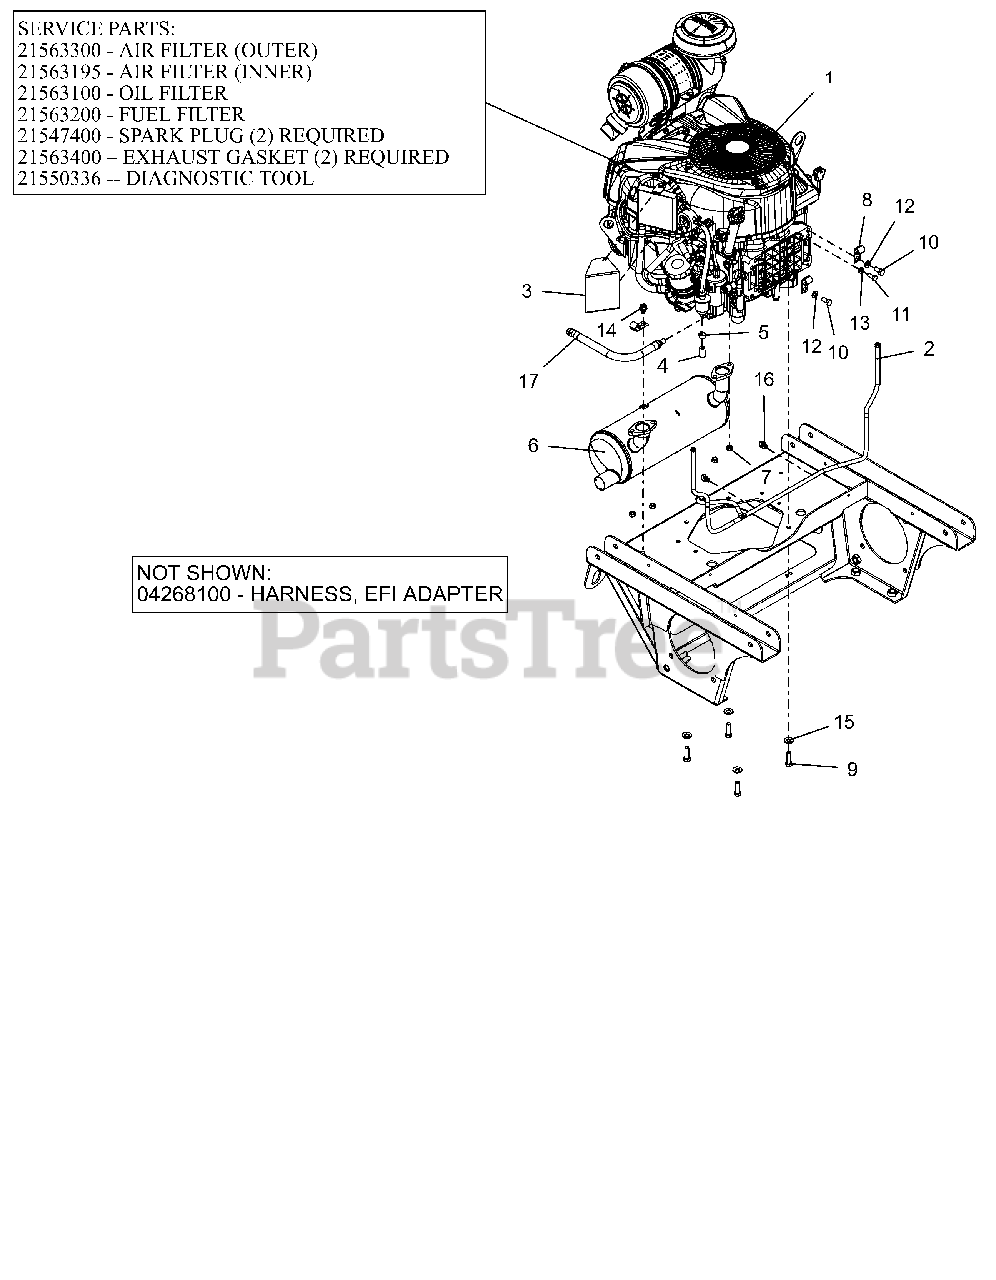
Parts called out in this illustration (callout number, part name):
1	ENGINE, YAMAHA MX775V-EFI
1	AIR FILTER (OUTER) - YAMAHA
1	AIR FILTER (INNER) - YAMAHA
1	FILTER, OIL - YAMAHA 824
1	FILTER-FUEL YAMAHA 824
1	PLUG, SPARK
1	GASKET, MUFFLER YAMAHA 824
1	DIAGOSTIC TOOL, YAMAHA MXV
2	ASM, YAMAHA VAPOR LINE
3	DEFLECTOR,YAMAH OIL COOLER AIR
4	HOSE, .25 LOW-PERM BULK GAS
5	CLAMP, FUEL LINE
6	MUFFLER, YAMAHA
7	NUT-LK-TOP M8-1.25 YWZC
9	BLT-HEX.38-16X1.25 G5YZ NYTORQ
10	@BLT-HEX .38-16X.75 GR5 YWZC
11	@BLT-HEX .31-18X.75 GR5 YWZC
12	@WSHR-LK .38X.094 REG YWZC
13	@WSHR-LK .31X.078 REG YWZC
14	@SCR-TAP .38-16X.50 HWH TR YWZ
15	WASHER, 3/8" SPRING DISC
16	ROUTING CLIP (1/2" ID)
17	HOSE, OIL DRAIN
18	HARNESS, EFI ADAPTER
